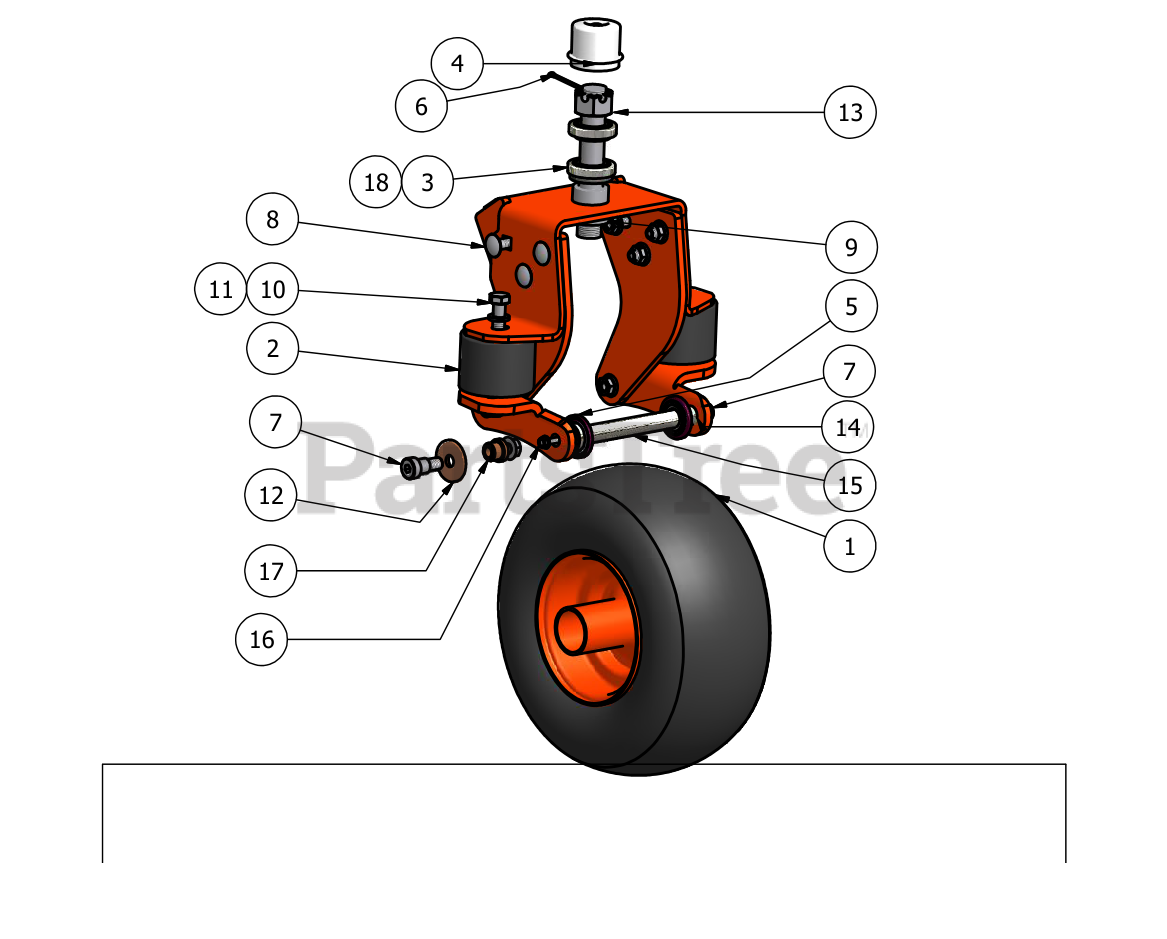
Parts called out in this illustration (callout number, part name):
1	13"x6.50-6 Tire &Wheel
2	Rubber Isolator
4	Dust Cover
5	5/8" Bearing
6	Cotter Pin
7	5/8"x5/8" Shoulder Bolt
8	1/2"x1 1/4"Carrige Bolt
9	1/2" Flange Nut
10	1/2" 1 1/2" Hex Bolt
11	1/2" Lock Washer
12	5/8" Flat Washer
13	1" Fine Threaded Castle Nut
14	1/2" Collar Spacer
15	7"x 1/2" ID Tire Spacer
16	1/2" x 10" Bolt
17	5/8" Shoulder Bushing
